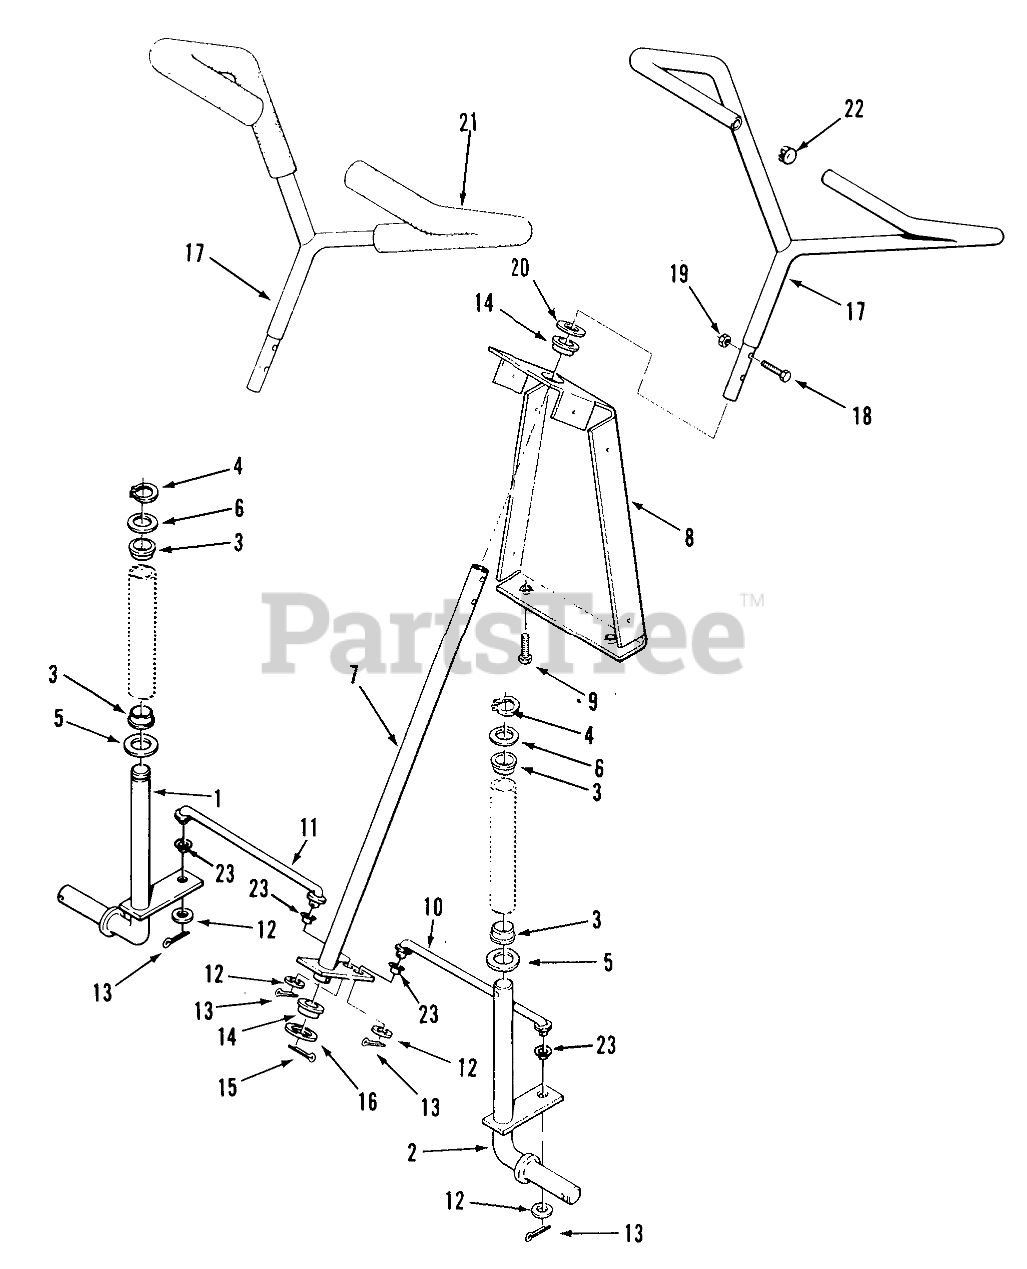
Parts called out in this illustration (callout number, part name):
1	ASS'Y-SPINDLE RH. R
2	FRONT SPINDLE ASSY LH R
3	BUSHING
4	Snap Ring
5	Washer
6	WASHER
7	ASSY STEERING SHA R
8	SUPPORT-STG UPPER B
9	Screw
10	TIE ROD LH R
11	TIE ROD RH R
12	Washer
13	Cotter Pin
14	BEARING
15	Cotter Pin
16	WASHER-FLAT
17	STEERING WHEEL
18	Bolt
19	Nut
20	Washer
21	Grips-Steering Wheel 112-6
22	PLUG BUTTON
23	BEARING
